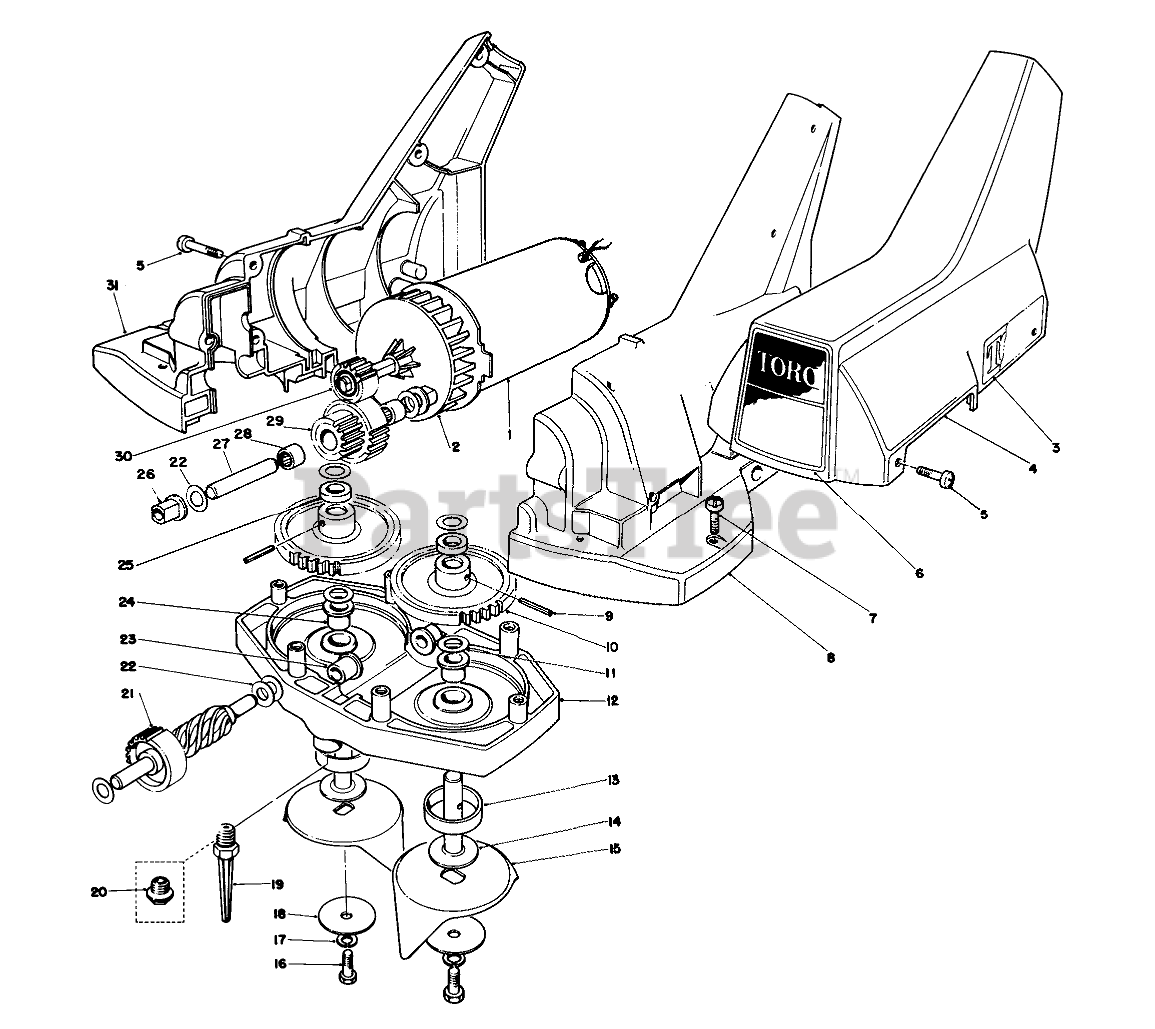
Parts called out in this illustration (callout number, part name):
3	DECAL - TORO
4	Cover
6	Decal
7	#10-32 PHILLIPS TF SC
8	Upper Case L.H.(Incl. Ref. #24)
9	PIN-GROOVED
10	HELICAL GEAR
11	THRUST RACE
12	Lower Case (Incl. Ref. #24)
13	SPACER
14	Tine Shaft
15	Tine Cup
16	1/4-20 X 5/8 CAPSCREW
17	WASHER-LOCK
18	WASHER-FLAT
19	STABILIZER SPIKE
22	THRUST WASHER
23	Bushing
24	BUSHING-FLANGE
25	COLLAR
26	Sleeve
27	Idler Shaft
28	Bearing
29	CLUSTER GEAR
31	Upper Case R.H. (Incl. Ref. #24)
